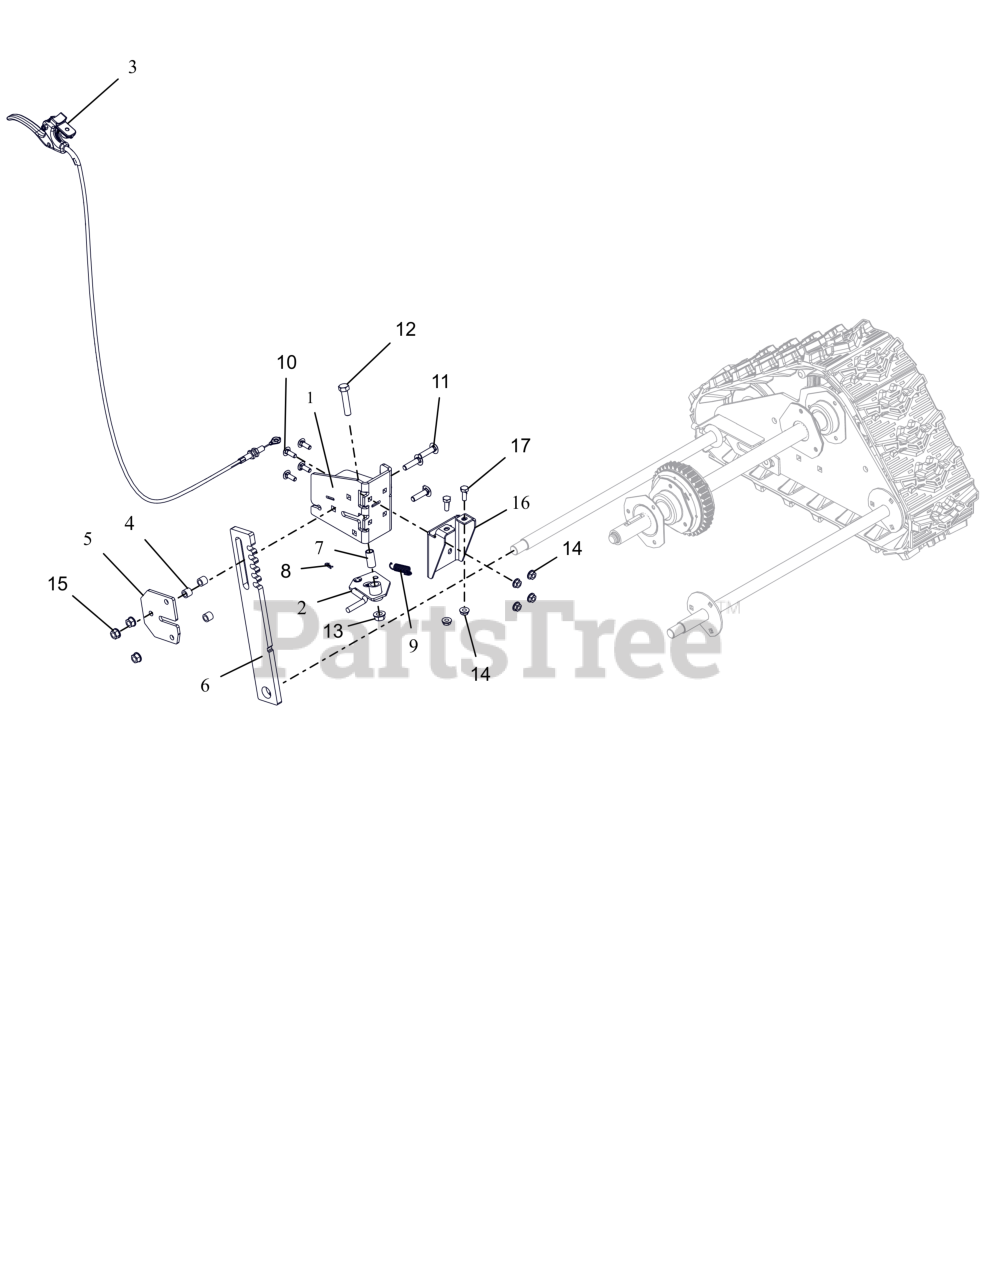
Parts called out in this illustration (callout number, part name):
1	BRACKET,HEIGHT ADJUSTER-DELUXE
2	LOCK,HEIGHT ADJUSTER TRIGGER
3	CABLE, TRACK REMOTE
4	SPACER .50 X .32 X .42
5	PLATE, HEIGHT ADJUSTER
6	STOP,HEIGHT ADJUSTER-DELUXE
7	BSHG-SLV .385X.500X1.045
8	PIN, HAIR #178 .06X.77 ZCC
9	SPRING-EXT .047 X .438 X 1.85
10	BLT, RHSN .25-20X.750 G5 ZCC
11	BLT, RHSSN.31-18X1.25 G5 ZCC
12	BLT, HEX .38-16X1.75 G5 ZCC
13	NUT-LK-CTR-FLG .375-16 GF ZCC
14	NUT-LK-CTR-FLG .25-20 ZC120
15	NUT-LK-TOP-FLG .312-18 GF ZCC
16	BRACKET, REINFORCEMENT
17	BLT, HEX .25-20X.75 G5 ZCC
